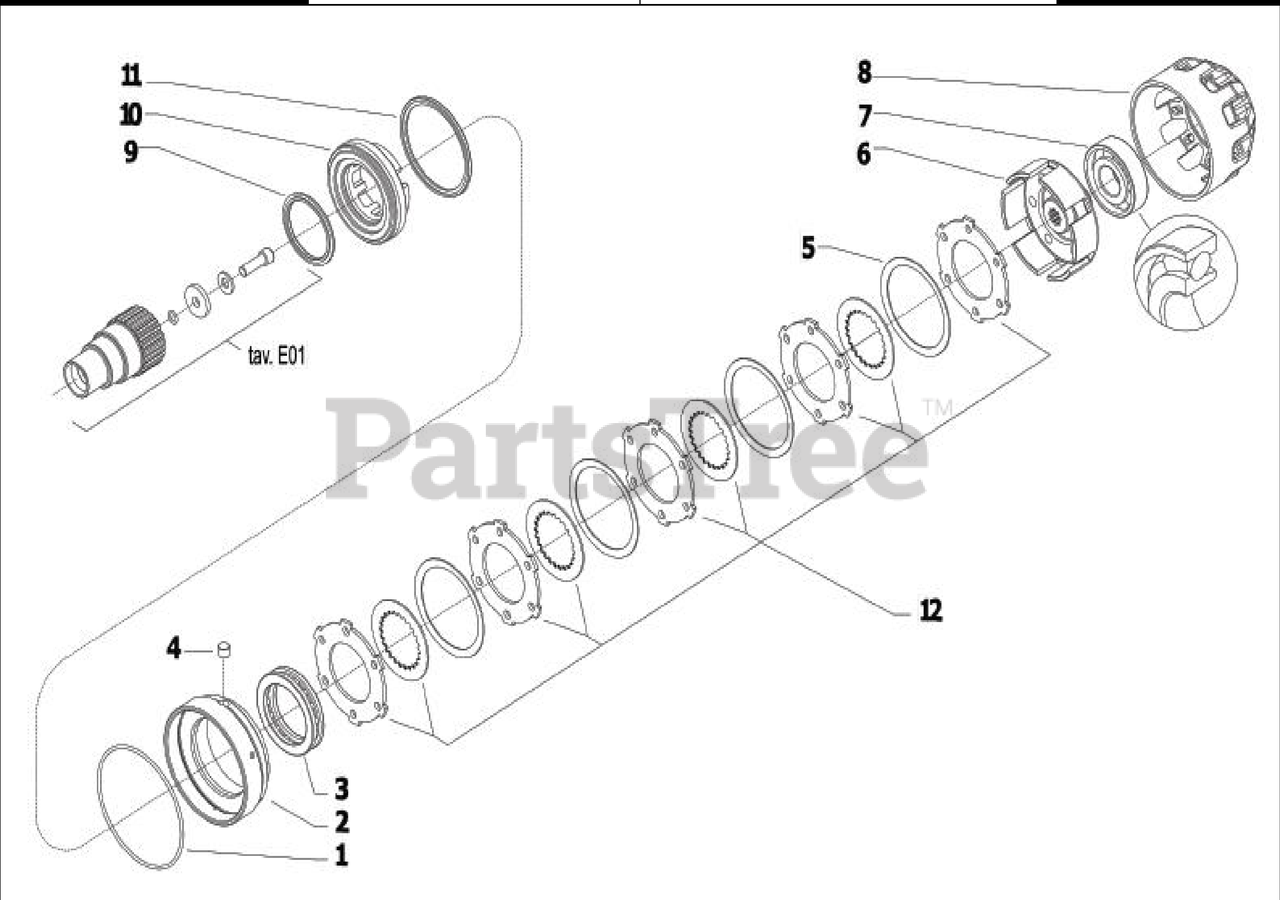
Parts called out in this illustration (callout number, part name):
1	O-RING OR 3375 (94,92X2,62)
2	BRAKE RING (LEFT HAND THREAD)
3	BEARING 51110 (50X70X14)
4	PIN 10MM
5	SPRING
6	CLUTCH BASKET
7	BEARING 7305-BJP OBL 25x62x17
8	HOUSING (LEFT HAND THREAD)
9	RING PTFE PRP 01A02-0500-A-32
10	PISTON
11	RING PTFE PRP02A02-0850-A-32-N
12	DISC SET (Springs # 5 not included 4 required)
